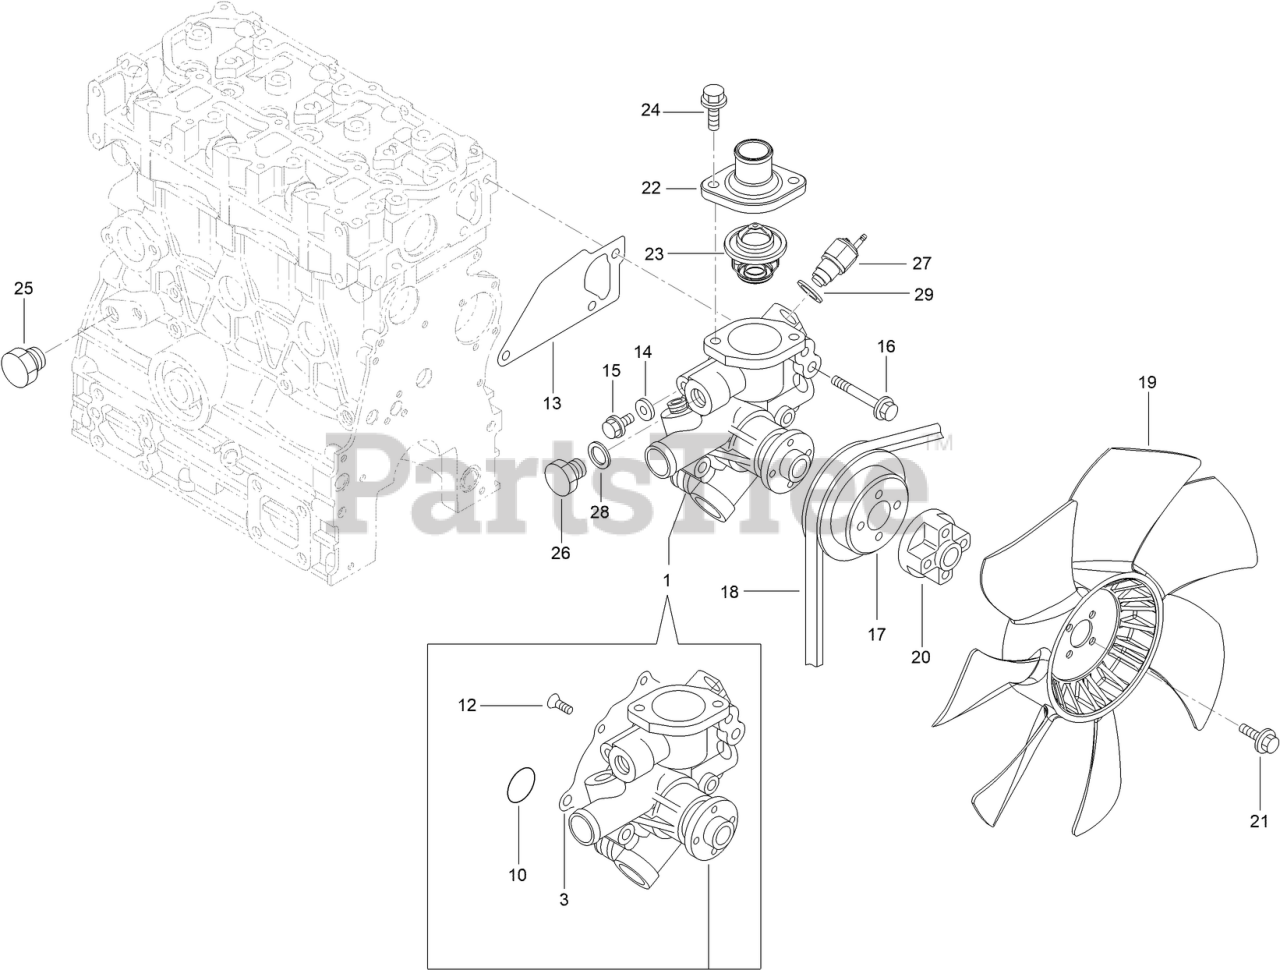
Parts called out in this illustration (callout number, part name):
1	CW PUMP ASM
3	GASKET
10	O-RING
13	GASKET-WATER PUMP
14	GASKET
17	V-PULLEY
18	V-BELT
19	FAN-COOLING
20	SPACER
22	COVER-THERMOSTAT
23	THERMOSTAT
25	PLUG-DRAIN
27	SWITCH, TEMPERATURE
28	GASKET
29	GASKET
